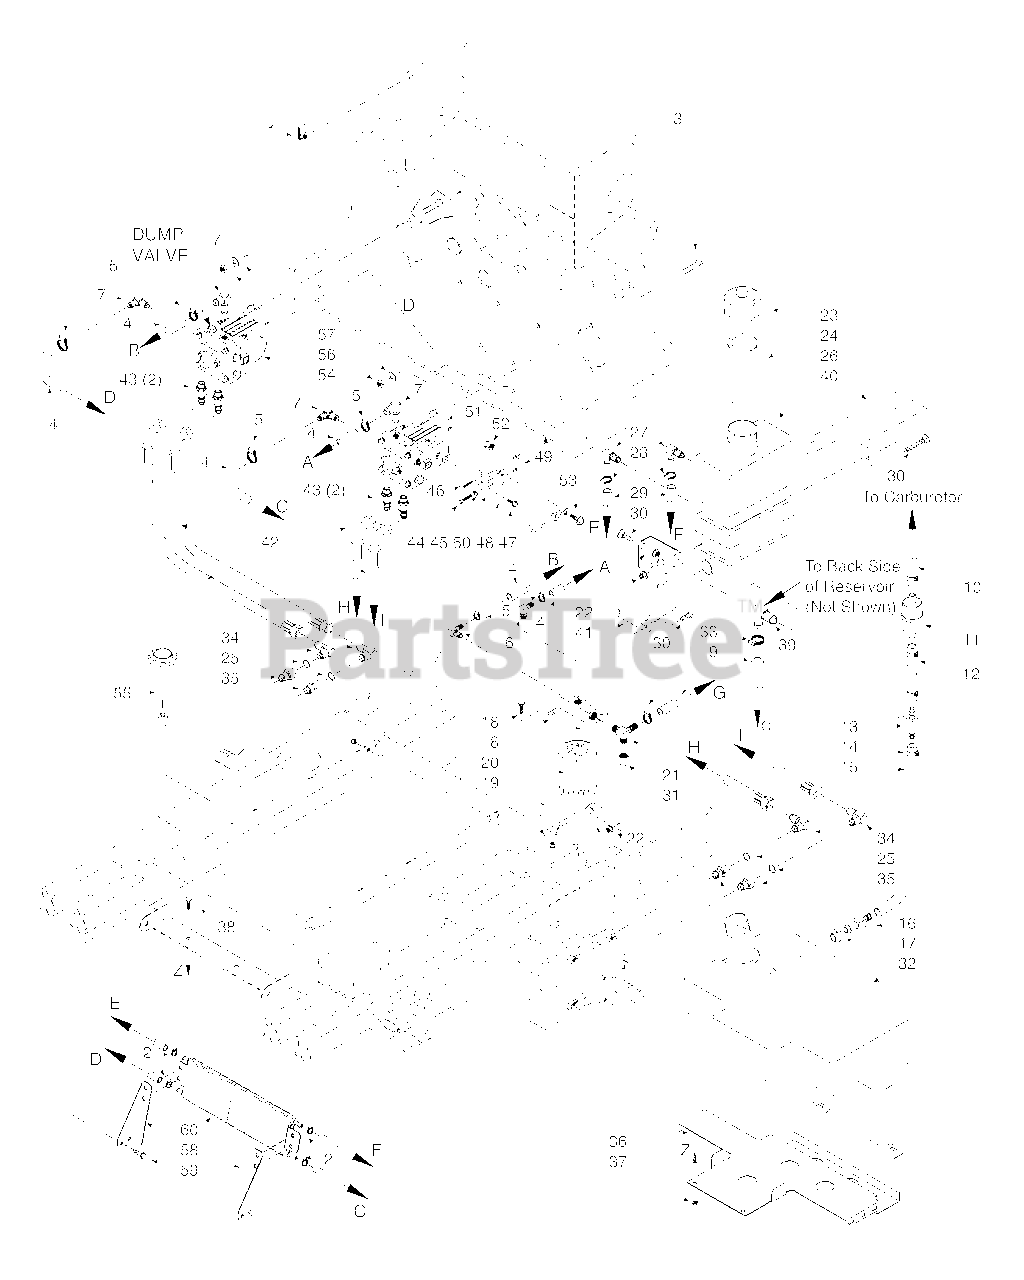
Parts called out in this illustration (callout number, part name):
1	U-Nut 1/4-20
2	Hose Clamp, 0.69 dia.
3	Bolt, Hex Head 1/4-20 x 2.0"
4	Hose, 3/8" ID Pushlock - (order by inch)
5	Clamp, Hose 1/2"
6	Elbow, 90 Degree - 1/4 NPT x 3/8 Hose
7	Elbow, 90 Degree - 9/16 O-ring x 3/8 Hose
8	Oil Filter Base
9	Hose Assembly, 1/2" ID (Tank to Filter Base)
10	Fuel Hose to Carb.
11	Fuel Filter
12	Fuel Hose, 1/4" ID. (order by inch)
13	Valve, Shutoff Kohler
14	Clamp, Fuel Hose
15	Fuel Hose, 1/4" ID. (order by inch)
16	Hose Fitting
17	Bushing
18	Bolt, Hex Head 5/16-18 x1.0" Zinc
19	Nut, Serrated Flange 5/16-18
20	Oil Filter
21	Tee, 3/4 O-ring x JIC x 1/2" Hose
22	Nut, Hex Elastic Stop 1/4-20
23	Cap, Hydraulic Tank
24	Insert, Filler Neck
25	O-Ring
26	Oil Reservoir Assembly
27	Elbow, 90 Degree .38 Hose
28	Hose Clamp, 0.69 dia.
29	Hose, 3/8" ID, Pushlock (order by inch)
30	Screw, Phillips Head, 1/4-20
32	Fuel Tank Assembly
33	Clamp, Hose
34	Elbow, 90 Degree,1/2 x 1/2
35	Bushing, 7/8-14 JIC x 3/4-16 O-Ring
36	Support Bracket, Fuel Tank
37	Nut, 5/16-18 Serrated Flange
38	Bolt, Carriage 1/4-20 x 3/4"
39	Elbow, 90 Degree
40	Strap, Hydraulic Tank
41	Support Bracket, Hydraulic Tank
42	Hose Assembly, Pump
43	Union, 3/4-16 JIC x 3/4-16 O-ring
44	Bolt, Hex Head, 1/4-20 x 1-14"
45	Lockwasher, 1/4" Spring
46	Roll Pin, Spring 3/16 x 3/4"
47	Bolt, Hex Serrated Flange, 1/4-20 x 3/4"
48	Clamp, .69 Dia.
49	Clamp Plate, Pump Control
50	Block, Pump Control
51	Pump, Left Hand, BDP-16A-410
52	Nut, Hex, Elastic Stop 3/8-16
53	Bolt, Hex Head, 3/8-16 x 1-1/4
54	Pump, Right Hand, BDP 16A-307
55	Cap, Fuel Tank W/Guage
56	Nut, Hex Elastic Stop 3/8-16
57	Flatwasher, 3/8" (.391 x .938 x .105) Grade 8
58	Mounting Bracket - LH, Oil Cooler
59	Bolt, Hex Head 5/16-18 x 3/4"
60	Cooler, Oil
